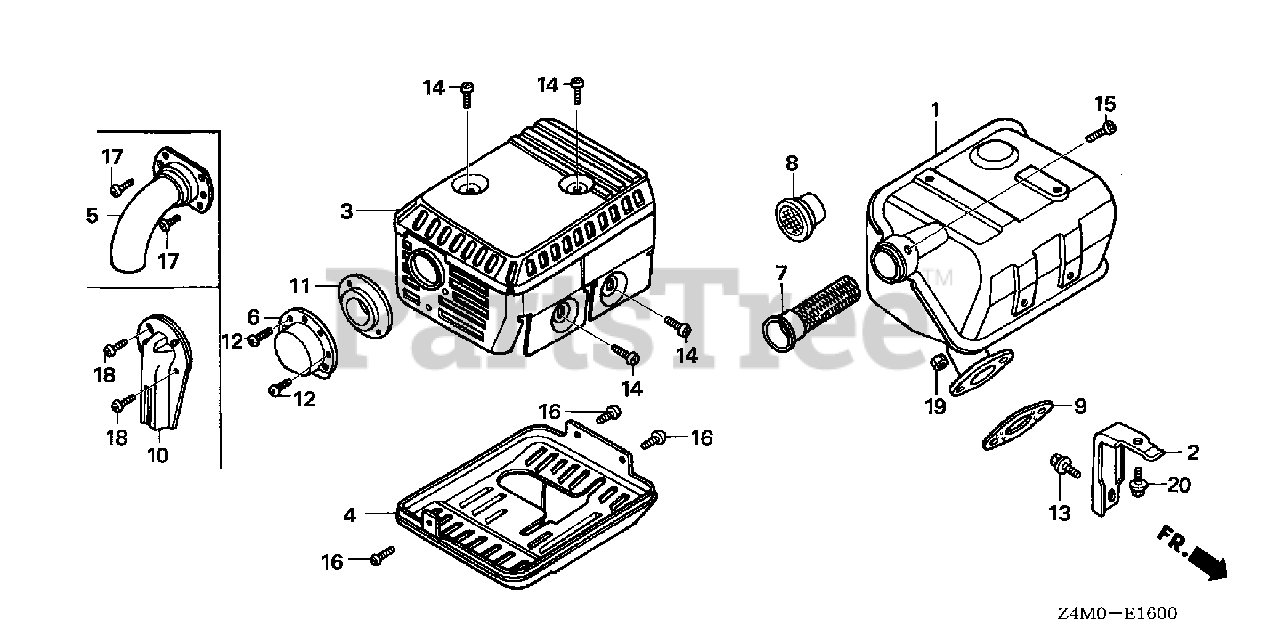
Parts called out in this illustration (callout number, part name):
1	MUFFLER (SILENT)
1	MUFFLER
2	STAY, MUFFLER
3	PROTECTOR, MUFFLER
5	CAP, MUFFLER
7	ARRESTER, SPARK
7	ARRESTER, SPARK (SILENT)
9	GASKET, MUFFLER
10	DEFLECTOR, MUFFLER
13	BOLT, FLANGE (6X13)
14	SCREW, TAPPING (5X8)
15	SCREW, TAPPING (4X6)
17	SCREW, TAPPING (4X6)
18	SCREW, TAPPING (4X6)
19	NUT, HEX. (8MM)
20	BOLT, FLANGE (6X12)
